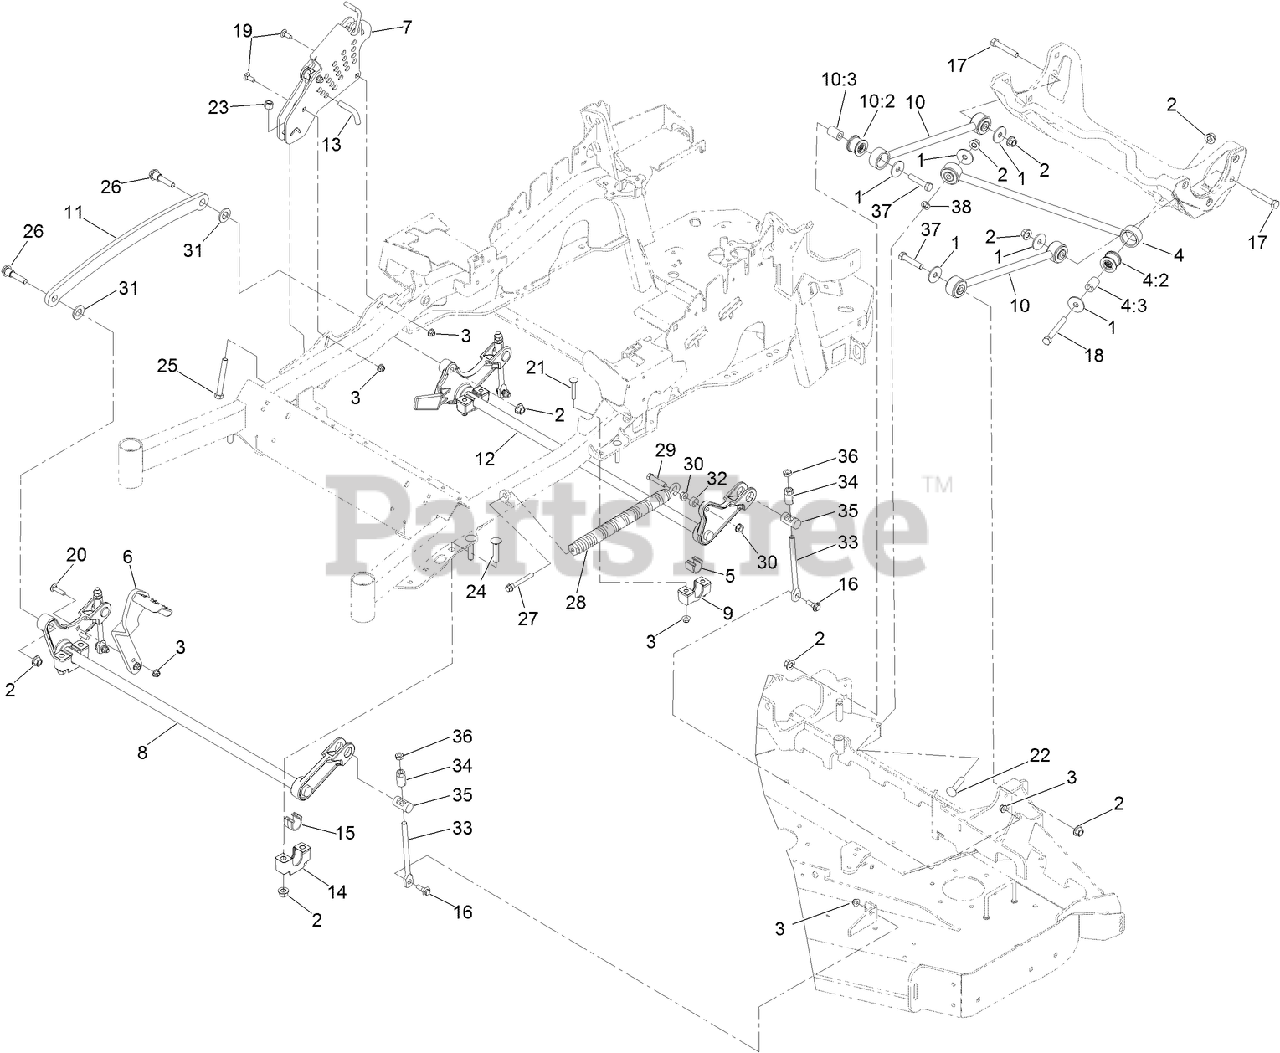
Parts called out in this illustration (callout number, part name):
1	WASHER-THRUST
2	NUT-LOCK
3	NUT-HF, NI
4	PANHARD ROD ASM
4:2	BUSHING-SUSPENSION, RUBBER
4:3	SPACER
5	BEARING-CROSS SHAFT, REAR
6	LEVER-FOOT
7	HEIGHT-OF-CUT ASM
8	DECKLIFT-FRONT
9	SUPPORT-CROSS SHAFT, BEARING REAR
10	DECK STRUT ASM
10:2	BUSHING-SUSPENSION, RUBBER
10:3	SPACER
11	LINK-LIFT, DECK
12	LIFT-DECK, REAR
13	PIN-HOC
14	SUPPORT-CROSS SHAFT, BEARING
15	BEARING-CROSS SHAFT, FRONT
16	SCREW-SHOULDER, HHF
17	SCREW-HH
18	SCREW-HH
19	BOLT-CARR
20	SCREW-CARR
21	SCREW-CARR
22	SCREW-CARR
23	NUT-LOCK, NI
24	BOLT-CARR
25	BOLT-TAP
26	SCREW-HHF, SHOULDER
27	BOLT-SHOULDER
28	SPRING-EXTENSION
29	SCREW-HH
30	NUT-HF
31	WASHER-FLAT
32	SPACER
33	LINK-ADJUSTER, DECK LIFT
34	ADJUSTER-LIFT, DECK
35	TRUNNION
36	NUT-JAM
37	SCREW-HH
38	NUT-PUSH
